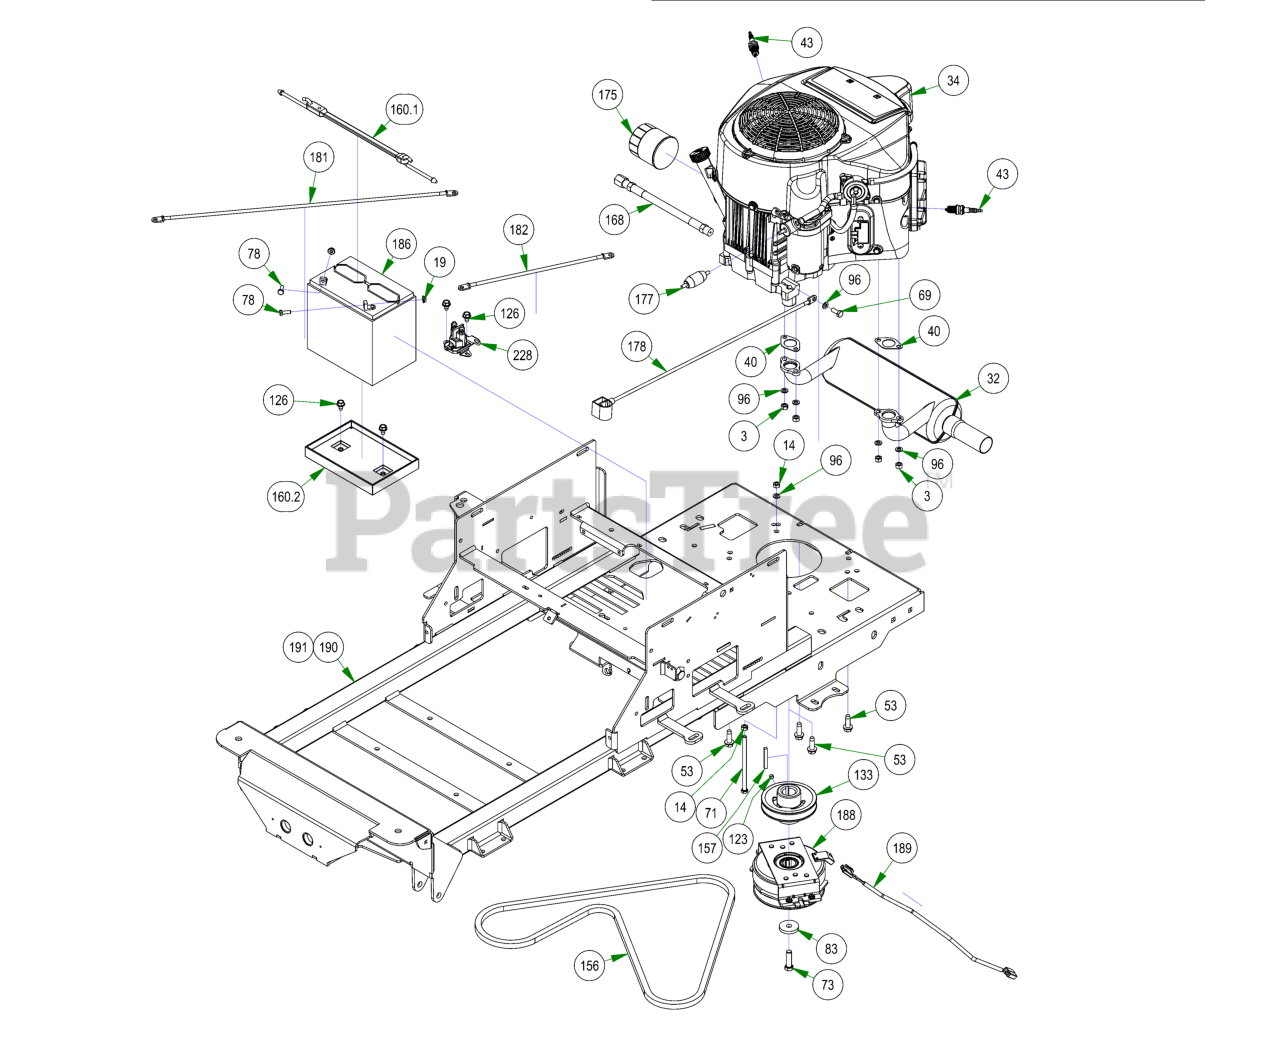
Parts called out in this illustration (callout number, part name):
3	M8-1.25 DIN 934 HEX NUT (CL.8) ZINC
14	5/16-18 HEX NUT ZINC
19	1/4-20 HEX SERRATED FLANGE NUT HARD/ZINC
32	Kawasaki Muffler 1251
34	FR 730V-S16 Kawasaki Engine 1.125" shaft-ZT
40	Exhaust Gasket
43	Spark Plug - Kawasaki
53	3/8-16 X 1-1/8 HEX WASHER UNSLOT SERRATED (TRI-LOB) TRS ZINC YELLOW
69	M8-1.25 X 20MM DIN 933 HEX TAP BOLT (CL 8.8) ZINC
71	5/16-18 X 5-1/2 HEX CAP SCREW (GR.5) ZINC
73	7/16-20 X 1-1/2 HEX CAP SCREW (GR.8) w/ Patch
78	1/4-20 X 3/4 HEX CAP SCREW (GR.5) ZINC
83	CLUTCH WASHER
96	5/16 SPLIT LOCKWASHER ZINC
123	5/16-24 X 1/4 SOCKET SET SCREW (CUP PT) PLAIN
126	5/16-18 X 1/2 HWH unslot (F) tcs zinc
133	4 3/4 Motor Pulley
157	1/4 X 2 SQ MACHINERY KEY 1018 STL PLAIN
160	2023 Battery Hold Down Assembly Strap
160.1	2023 Rubber Battery Hold Down Strap
160.2	Battery Tray
168	Oil drain Hose
175	22-26 Kaw Oil Filter FR Engine
177	Universal Inline Fuel Filter
178	24 inch Black Cable – MZ/ZT
181	24" Red Battery Cable
182	12 in red battery cable
186	SP-35 Battery
189	Clutch Pigtail
190	2023 ZT Elite Frame- Painted
191	2023 ZT Elite Frame- Painted
